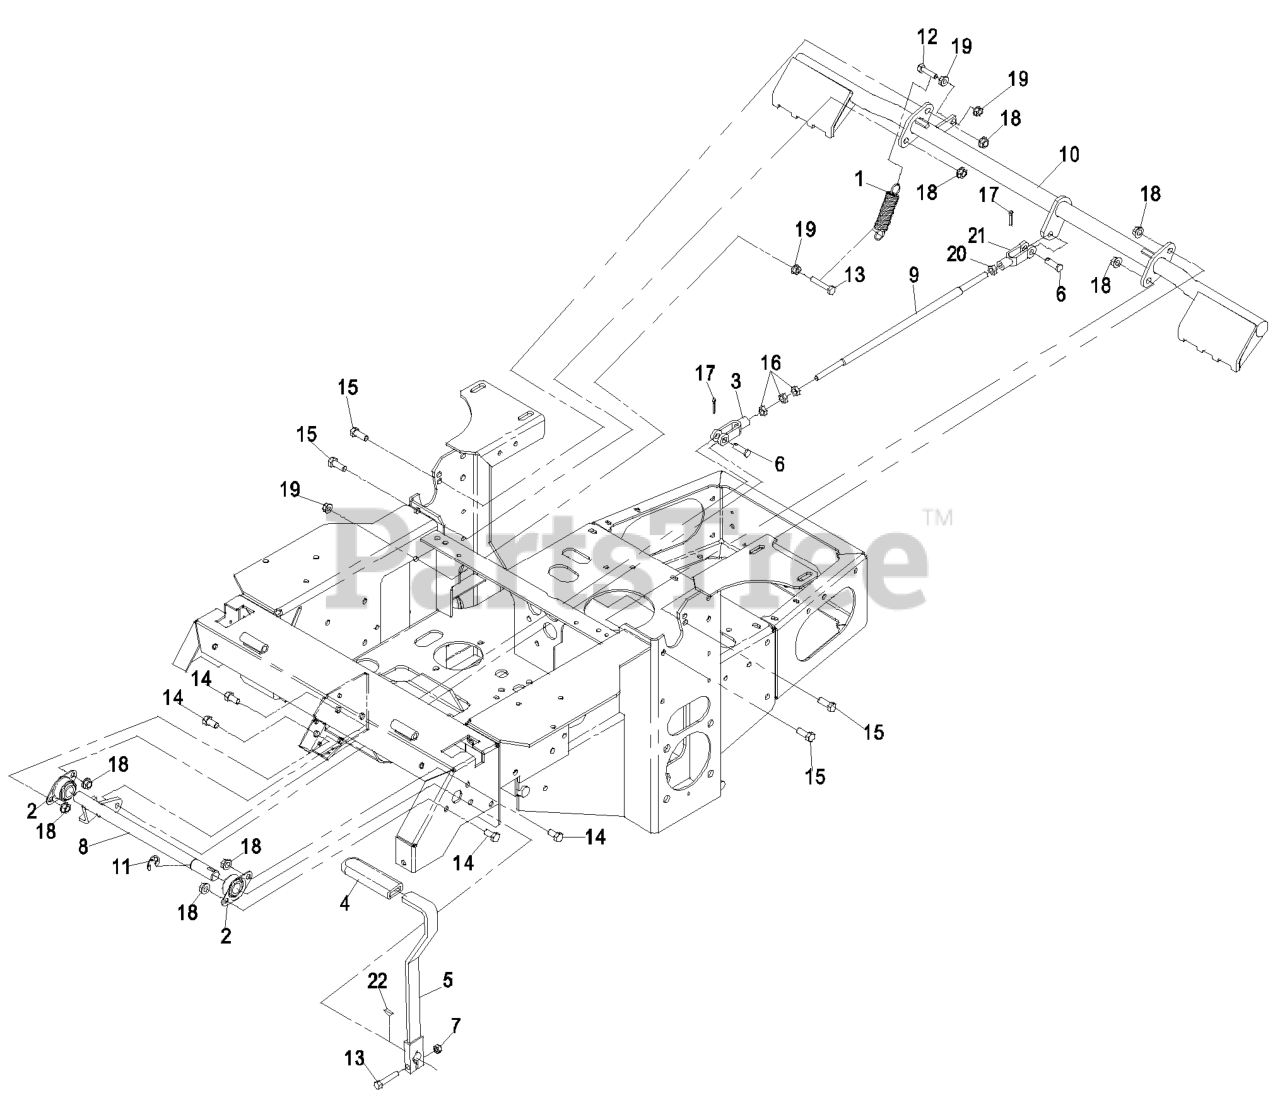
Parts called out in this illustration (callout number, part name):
1	SPRING-IDLER
2	BEARING-FLANGE, SIDE
3	YOKE-LINKAGE, BRAKE
4	GRIP-LEVER
5	HANDLE,PARK BRAKE W/GRIP
6	PIN-CLEVIS
7	NUTTORQUE ZKPLT
8	WELD,SHAFT/PARK BRAKE
9	LINKAGE, BRAKE (PLTD)
12	SCREW-HH
13	SCREW-HH
14	SCREW-HH
15	SCREW-HH
16	NUT-HEX
17	PIN-COTTER
18	NUT-HHF, WHIZ
20	NUT-HEX, LH
21	YOKE, LH YZ
22	KEY-WOODRUFF
